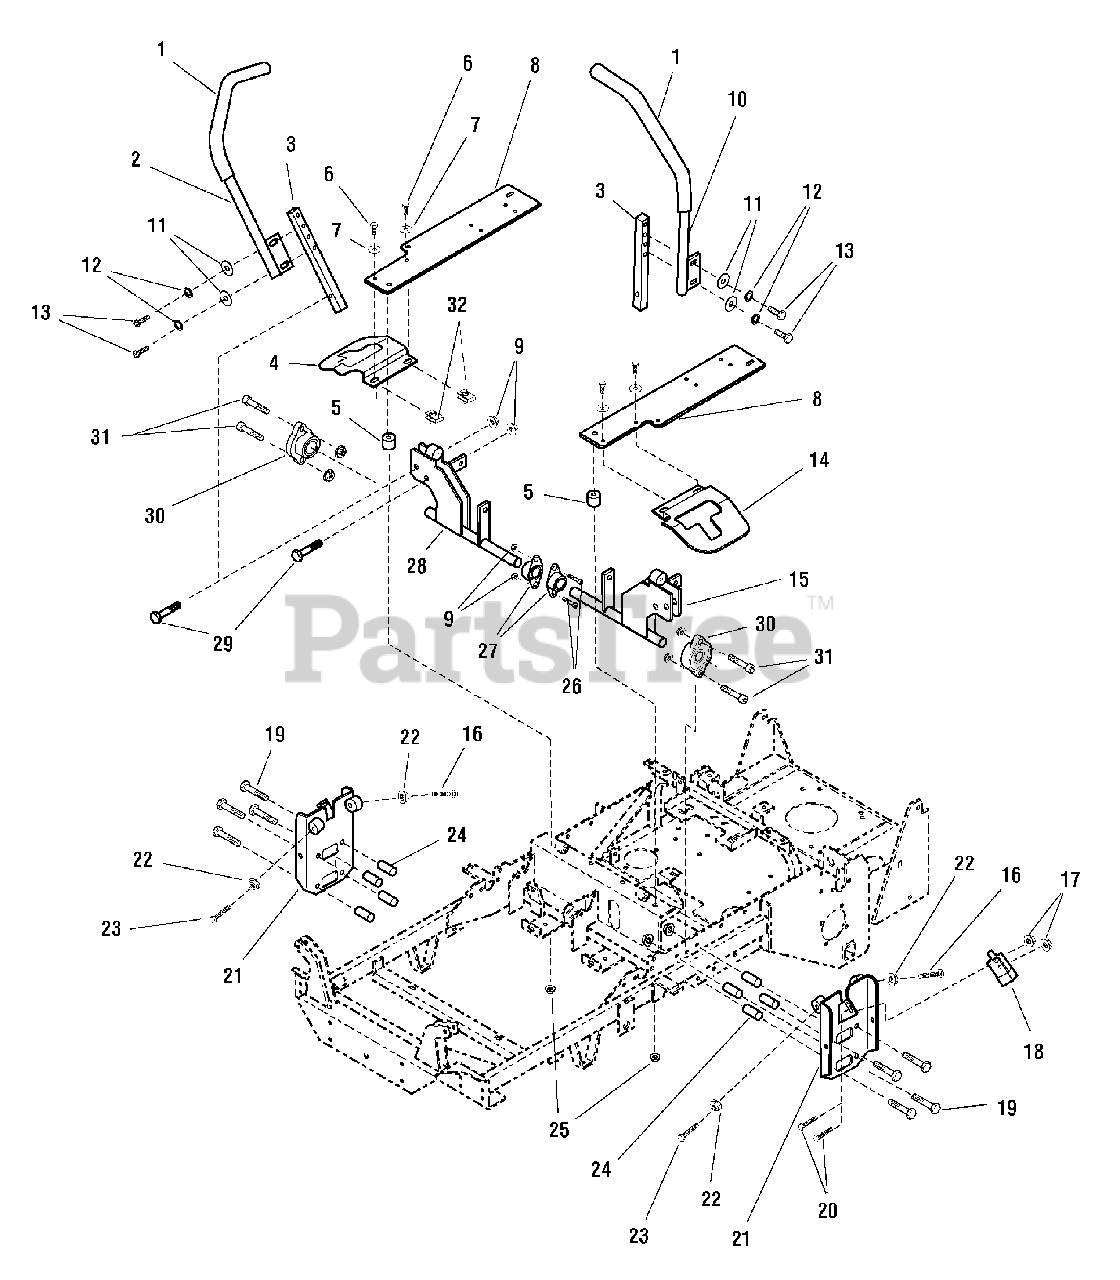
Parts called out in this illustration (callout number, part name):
2	WELD, HANDLE MOTION CONTROL, RH - BLK
3	MOUNT, CONTROL ARM - BLK
4	NEUTRAL LOCK PLATE COVER, RH, Orange
4	NEUTRAL LOCK PLATE COVER, RH, Red
6	CAPSCREW, Hex Head, 1/4-20 X 3/4
7	WASHER, 1/4 SAE (5025154)
8	SHIELD, Fan, Orange
8	SHIELD, Fan, Red
9	NUT, Hex Nylon Lock, 3/8-16
10	WELD, HANDLE MOTION CONTROL, LH - BLK
11	WASHER, Flat, 5/16
12	LOCK WASHER, 5/16
13	CAPSCREW, Hex Head, 5/16-18 X 1
14	NEUTRAL LOCK PLATE COVER, LH, Orange
14	NEUTRAL LOCK PLATE COVER, LH, Red
15	WELD, Control Shaft, LH, Orange
15	WELD, Control Shaft, LH, Red
16	CAPSCREW, Hex Head, Flange Lock Taptite, 5/16-18 X 2
17	NUT, Hex, #10-24
18	SWITCH, PLUNGER, N.O./N.C.
19	CAPSCREW, Hex Head, 5/16-18 X 2 1/4
20	SCREW, #10-24
21	WELD, Plate, Neutral, Orange
21	WELD, Plate, Neutral, Red
22	NUT, Hex Serrated Flange, 5/16-18
23	CAPSCREW, Hex Head, Flange Lock Taptite, 5/16-18 X 1-3/4
25	NUT, Hex, Serrated Flange, 3/8-16
26	CAPSCREW, 3/8-16 X 1
27	BEARING, Bronze
28	WELD, Control Shaft, RH, Orange
28	WELD, Control Shaft, RH, Red
29	CAPSCREW, Hex Head, 3/8-16 X 1 3/4
30	BEARING, Flange
31	CAPSCREW, Socket Head, 3/8-16 X 1 1/4
32	BODY CLIP, 1/4-20
